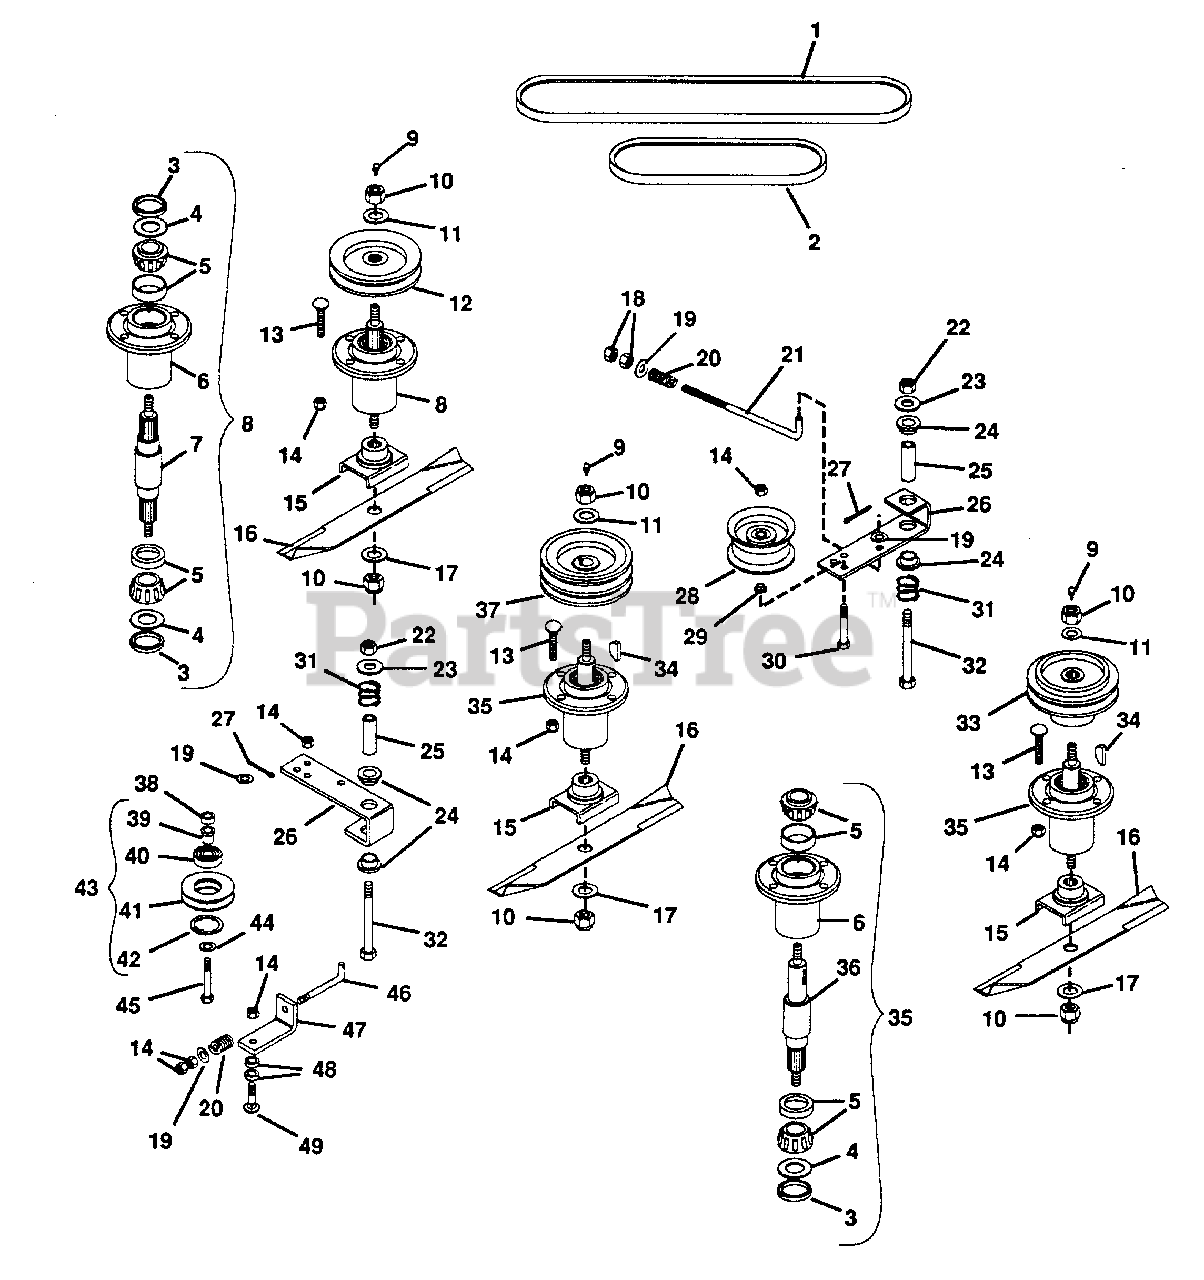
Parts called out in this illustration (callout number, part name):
1	Belt
2	Belt, V
3	Seal, Steel(in 34605)
3	Seal, Steel(in 21306)
4	Washer, Flat .975x1.970x.030(in 34605)
4	Washer, Flat .975x1.970x.030(in 21306)
5	Assembly, Bearing
6	Housing, Bearing
7	Shaft, Spindle
8	Assembly, Spindle
9	Fitting, Lube 1/8
10	Nut, Lock 5/8-11
11	Washer, Flat .687x1.312x.122
12	Pulley
13	Bolt, 3/8-16x1.375 Rd Hd Sq Nk
14	Nut, Lock 3/8-16
15	Weldment, Blade Cradle
16	Blade
17	Washer, Flat .656x1.312x.095
18	Nut, Hex 3/8-24
19	Washer, Flat .406x.812x.065
20	Spring, Comp. 1x.78
21	Rod, Idler
22	Nut, Lock 1/2-13
23	Washer, Flat .531x1.250x.100
24	Bushing, Nylon .76x1x.6 Flg.
25	Spacer
26	Arm, Idler Pivot
27	Pin, Cotter .09x.75
28	Pulley, Idler
29	Bushing
30	Bolt, Hex 3/8-16x2.25
31	Spring, Comp. 1x.80x36 Lb/N
32	Bolt, Hex 1/2-13x3.25
33	Sheave, Spindle
34	Key, Woodruff .250x1 Hard #15
35	Assembly, Spindle
36	Shaft, Spindle
37	Sheave, Spindle
38	Spacer, Idler .406x.625x.48
39	Bushing, Idler Sheave
40	Bearing, Ball
41	Sheave, Idler
42	Ring, Retaining
43	Assembly, Idler Sheave
44	Washer, Flat .375x1.125x.065
45	Bolt, Hex 3/8-16x2.00
46	Rod, Idler
47	Bracket, Belt Tensioner
48	Spacer
49	Bolt, 3/8-16x1.75 Rd Hd Sq Nk
